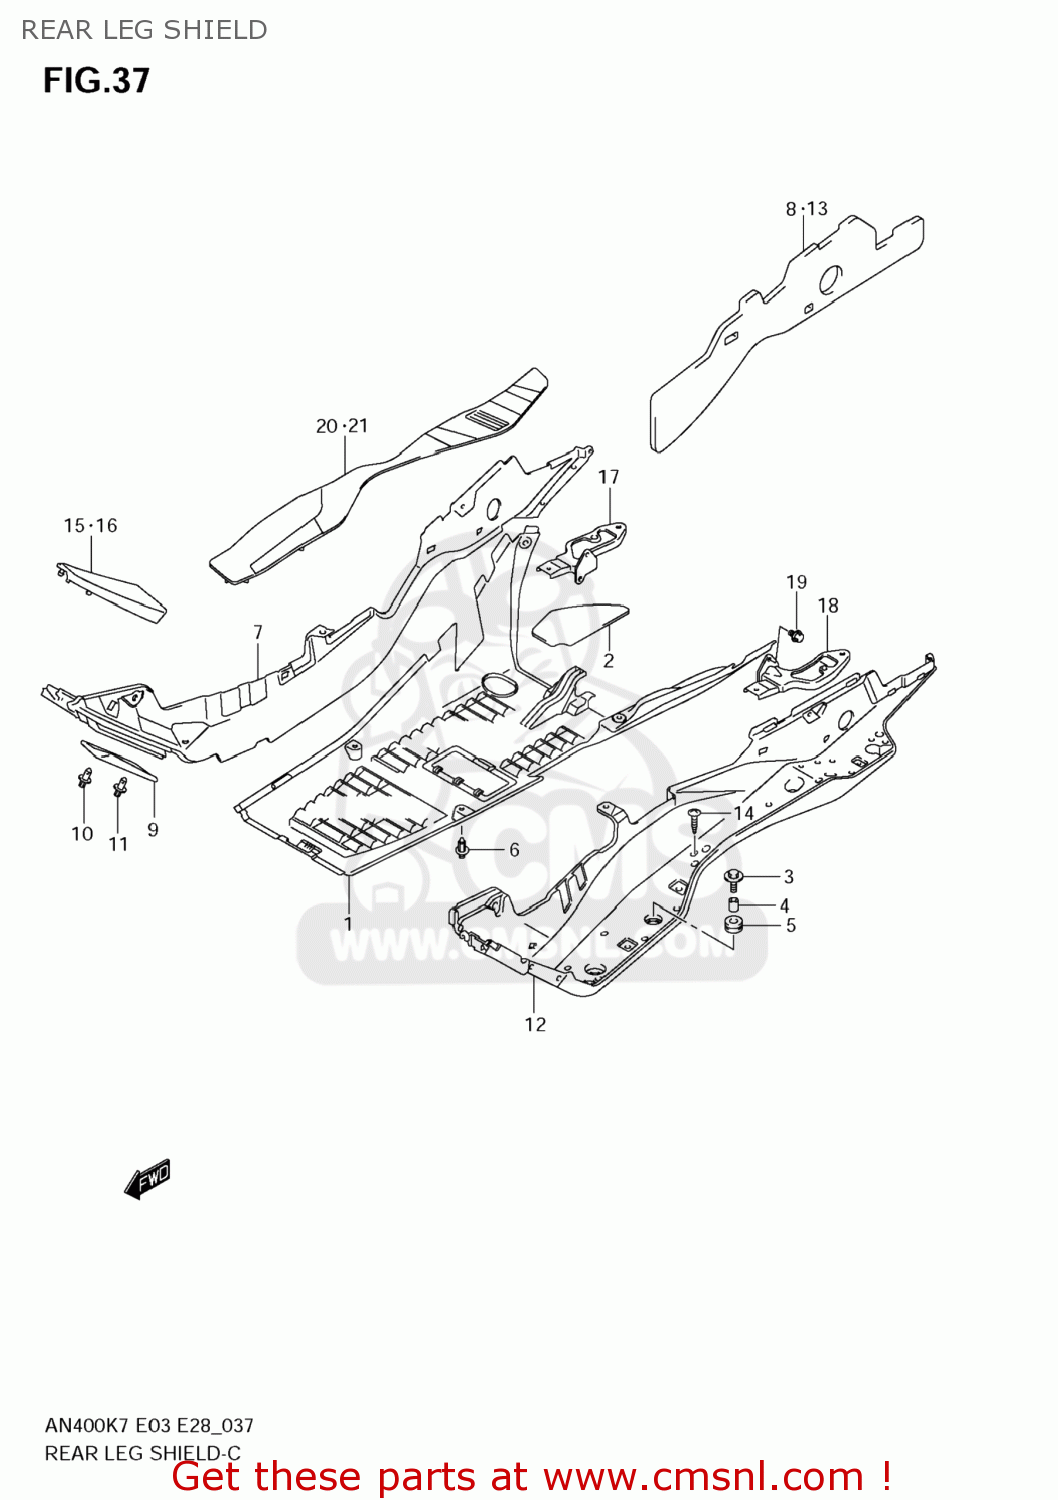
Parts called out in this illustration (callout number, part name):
1	COVER,UNDER CTR
2	CUSHION,UNDER COVER
3	BOLT(6X25)
4	SPACER(8.5X12X11)
5	CUSHION
6	CLIP(BLACK)
7	FOOTBOARD,R(BL
8	CUSHION,FOOTBOARD,R
9	COVER,FOOTBOARD,R
10	CLIP(BLACK)
11	CLIP(BLACK)
12	FOOTBOARD,L(BL
13	CUSHION,FOOTBOARD,L
14	SCREW
15	MAT,FLOOR FR,R
16	MAT,FLOOR FR,L
17	BRACKET,PILLION,R
18	BRACKET,PILLION,L
19	BOLT
20	MAT,FLOOR RR,R
21	MAT,FLOOR RR,L
